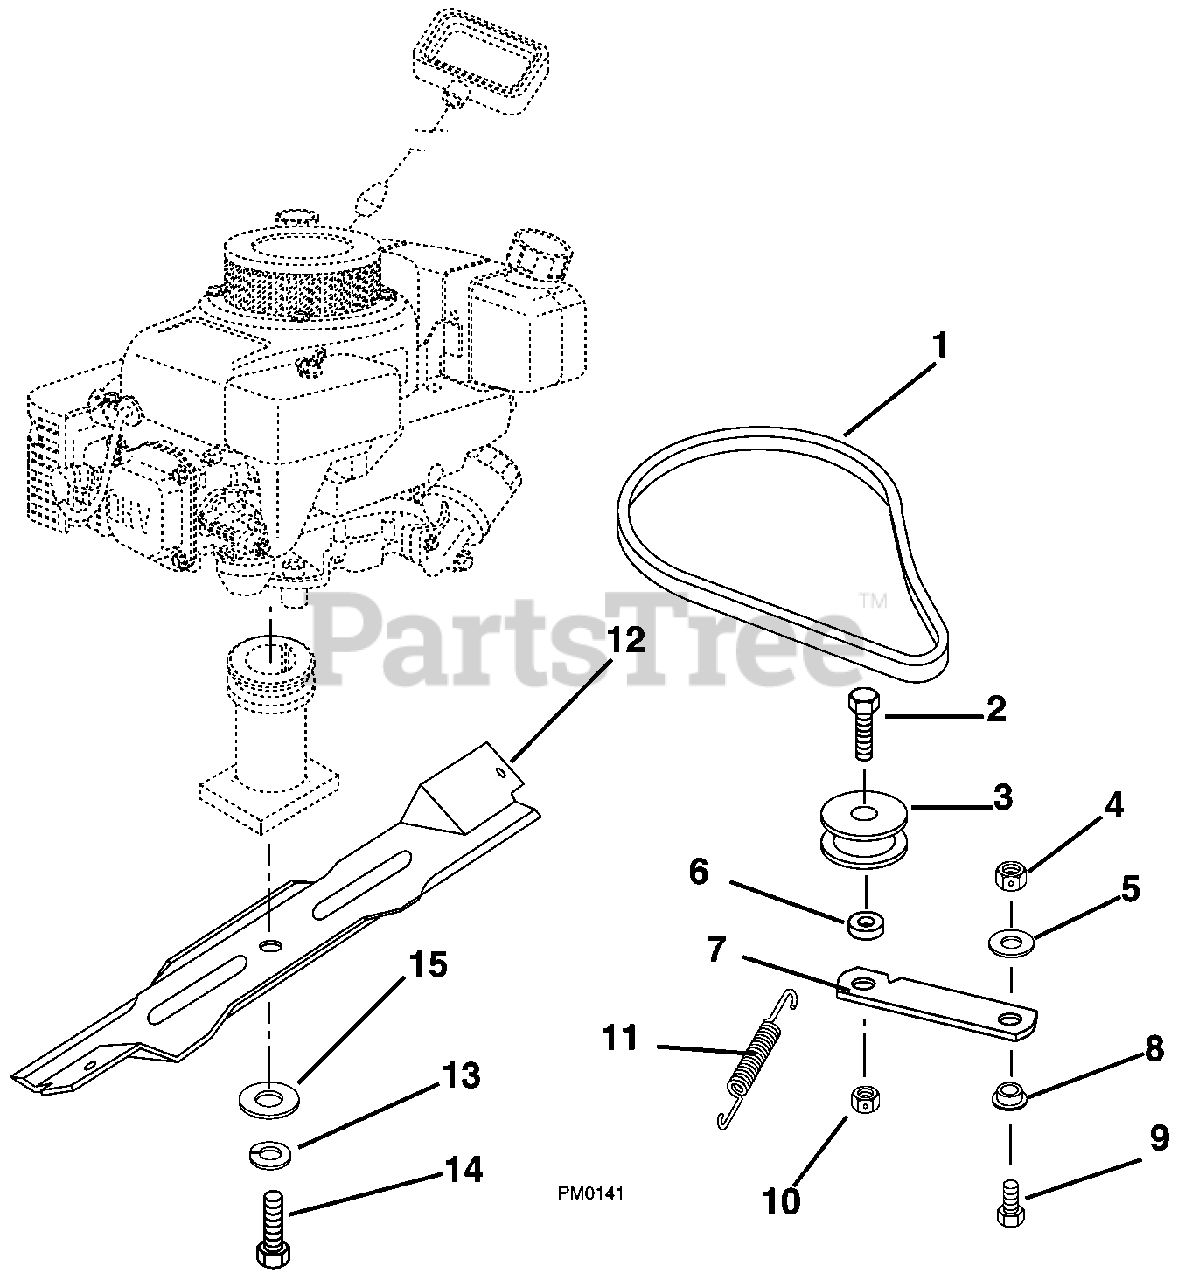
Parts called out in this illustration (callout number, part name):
1	V-Belt 3L Section (580 RS, 580 RSE, 580 RSW, 600 C)
2	Bolt-Hex .44-14 x 1.25 Grade 5 (580 RS, 580 RSE, 580 RSW, 600 C)
3	Idler-Flat 1.75 x .47 (580 RS, 580 RSE, 580 RSW, 600 C)
4	Nut-Locking-Center .31 -18 (580 RS, 580 RSE, 580 RSW, 600 C)
5	Washer-Flat-Steel .323 x .625 x .062 (580 RS, 580 RSE, 580 RSW, 600 C)
6	Spacer .52 x .45 x .34 (580 RS, 580 RSE, 580 RSW, 600 C)
7	Idler Arm (580 RS, 580 RSE, 580 RSW, 600 C)
8	Bushing-Flange .325 x .501 x .250 x 1.120 (580 RS, 580 RSE, 580 RSW, 600 C)
9	Bolt-Hex .31-18 x .75 Grade 5 (580 RS, 580 RSE, 580 RSW, 580 BBC, 600 C)
10	Nut-Locking-Center .44-14 (580 RS, 580 RSE, 580 RSW, 600 C)
11	Spring, Tension .043 x .44 x 3.31 (580 RS, 580 RSE, 580 RSW, 600 C)
12	Blade, 21" Mower
13	Washer-Locking .38 x .094
14	Bolt-Hex .38-24 x 2.00 Grade 8
15	Washer-Flat Steel .390 x 1.50 x .125
